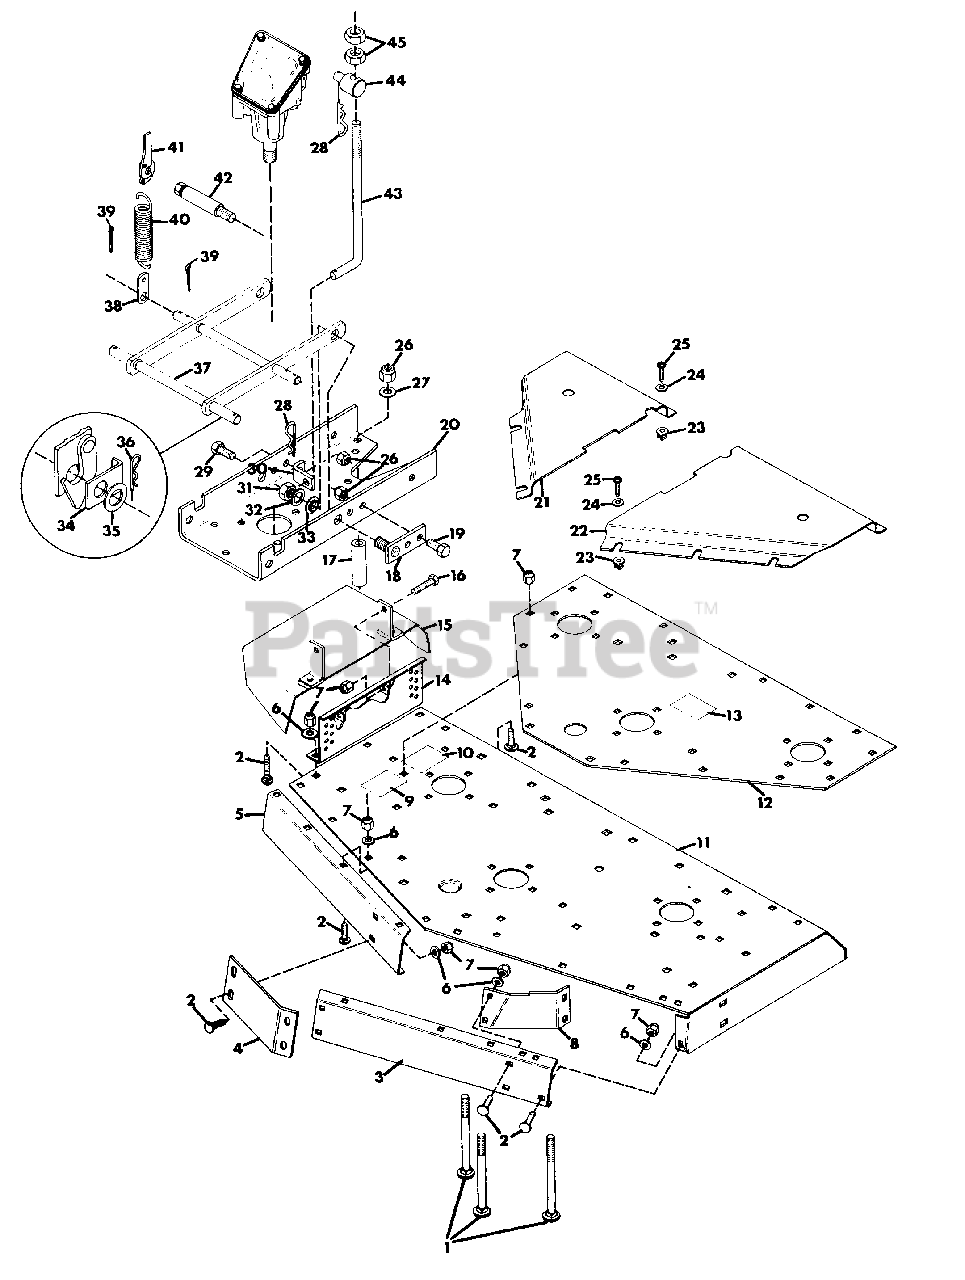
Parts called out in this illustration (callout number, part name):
1	BOLT, 1/2-13X3.50 RD HD SQ NK
2	BOLT, 3/8-16X1.00 RD HD SQ NK
3	PLATE, FRONT COVER L.H.
4	BRACKET, FRONT DECK
5	PLATE, FRONT COVER
6	WASHER, FLAT .406X.812X.065
7	NUT, LOCK 3/8-16
8	BAFFLE, FRONT
9	DECAL, WARNING EYE
10	DECAL, DANGER HAND
11	WELDMENT, 60" OFC
12	PLATE, DECK SUPPORT
13	DECAL, BELT DIAGRAM
14	WELDMENT, 60" HANGER
15	WELDMENT, DISCHARGE CHUTE
16	BOLT, HEX 3/8-16X1.25
17	SPACER, .850X.546X2.18
18	WELDMENT, PIVOT ANCHOR
19	BOLT, HEX 1/2-13X1.50
20	PLATE, SUPPORT
21	COVER, BELT R.H.
22	COVER, BELT L.H.
23	GROMMET, PLASTIC
24	WASHER, FLAT .281X.625X.065
25	SCREW, MACH. 1/4-20X.625 RD HD
26	NUT, LOCK 1/2-13
27	WASHER, FLAT .531X1.062X.095
28	PIN, COTTER HAIR
29	BOLT, HEX 1/2-13X1.75
30	BRACKET, LIFT
31	NUT, LOCK 3/4-10
32	RACE, BEARING THRUST
33	BUSHING, NYLON .76X1.00X.6 FLANGE
34	KEEPER, MOWER PIVOT
35	WASHER, FLAT .813X1.37X.100
36	PIN, HAIR
37	WELDMENT, PIVOT ARM
38	STRAP
39	PIN, COTTER .125X.1.125
40	SPRING, EXT. 7.625X1.50X70 RATE
41	LATCH, SPRING ASSEMBLY R.H.
42	LATCH, PIN
43	ROD, LIFT
44	PIVOT, MOWER LIFT
45	NUT, JAM 1/2-13 HEX
NS	STRIPE
NS	LATCH, SPRING ASSEMBLY L.H.
